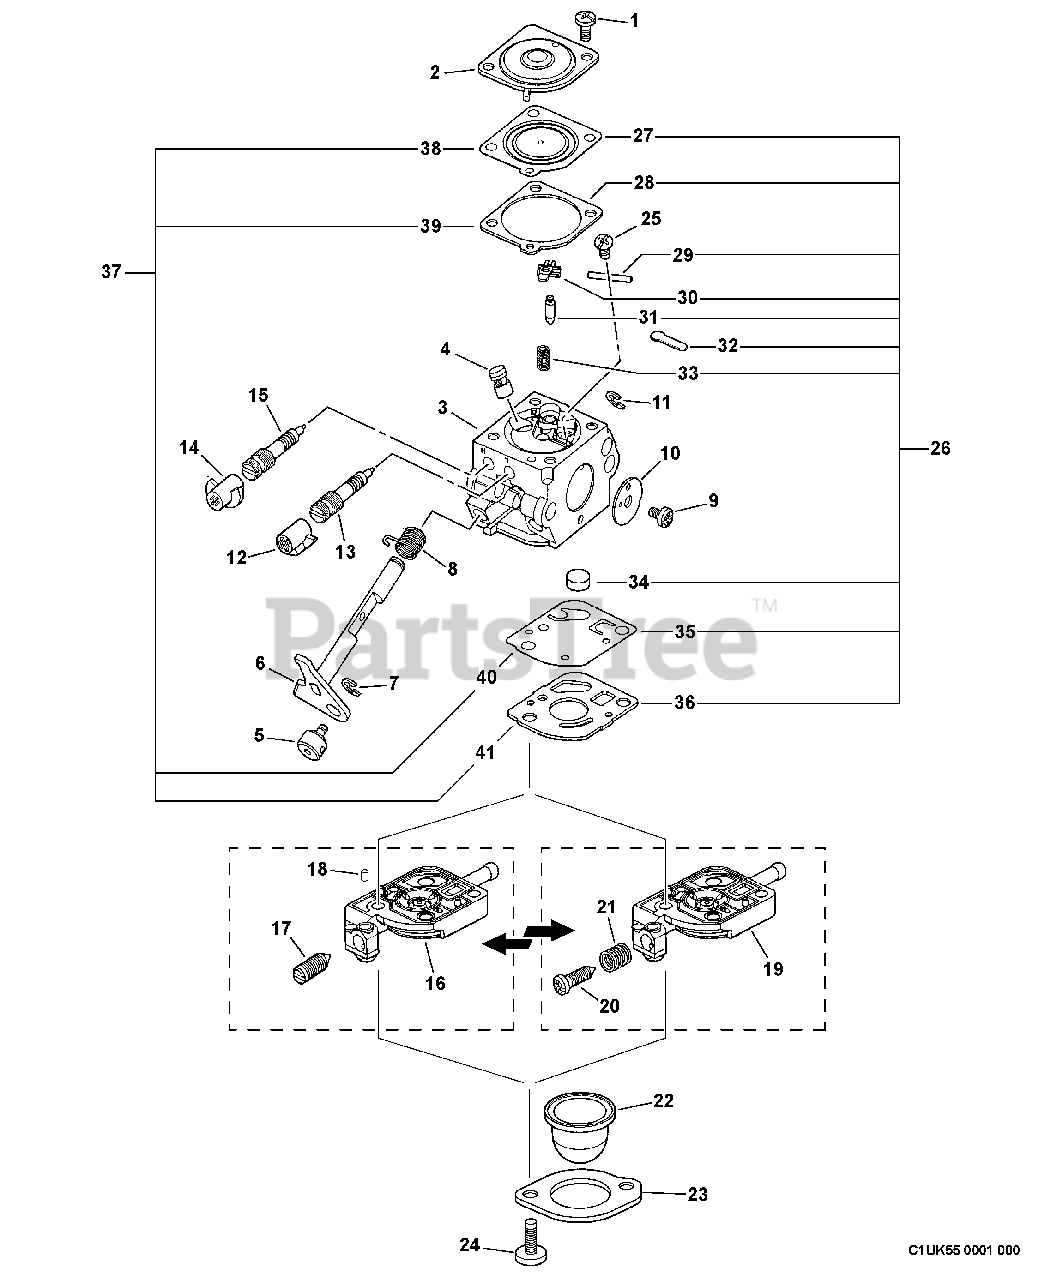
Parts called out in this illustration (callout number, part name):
2	COVER, METERING
3	BODY, CARBURETOR
4	NOZZLE, CHECK VALVE
6	SHAFT, THROTTLE
7	RING, RETAINING
8	SPRING, RETURN
10	VALVE, THROTTLE
11	RING, RETAINING
12	CAP, LIMITER
13	NEEDLE - LOW SPEED
14	CAP, LIMITER
15	NEEDLE - HIGH SPEED
16	BASE, PURGE
17	SCREW, IDLE ADJUST
18	PIECE, FRICTION
19	BASE, PURGE
20	SCREW, IDLE ADJUST
21	SPRING, IDLE ADJUST
22	BULB, PURGE
23	RETAINER, PURGE BULB
24	SCREW, RETAINER
25	SCREW, METERING LEVER PIN
26	REPAIR KIT
27	DIAPHRAGM, METERING
28	GASKET, DIAPHRAGM
29	PIN, METERING LEVER
30	LEVER, METERING
31	VALVE, INLET NEEDLE
32	PLUG, WELCH
33	SPRING, METERING LEVER
34	STRAINER
35	DIAPHRAGM, PUMP
36	GASKET, PUMP
37	DIAPHRAGM/GASKET KIT
38	DIAPHRAGM, METERING
39	GASKET, DIAPHRAGM
40	DIAPHRAGM, PUMP
41	GASKET, PUMP
